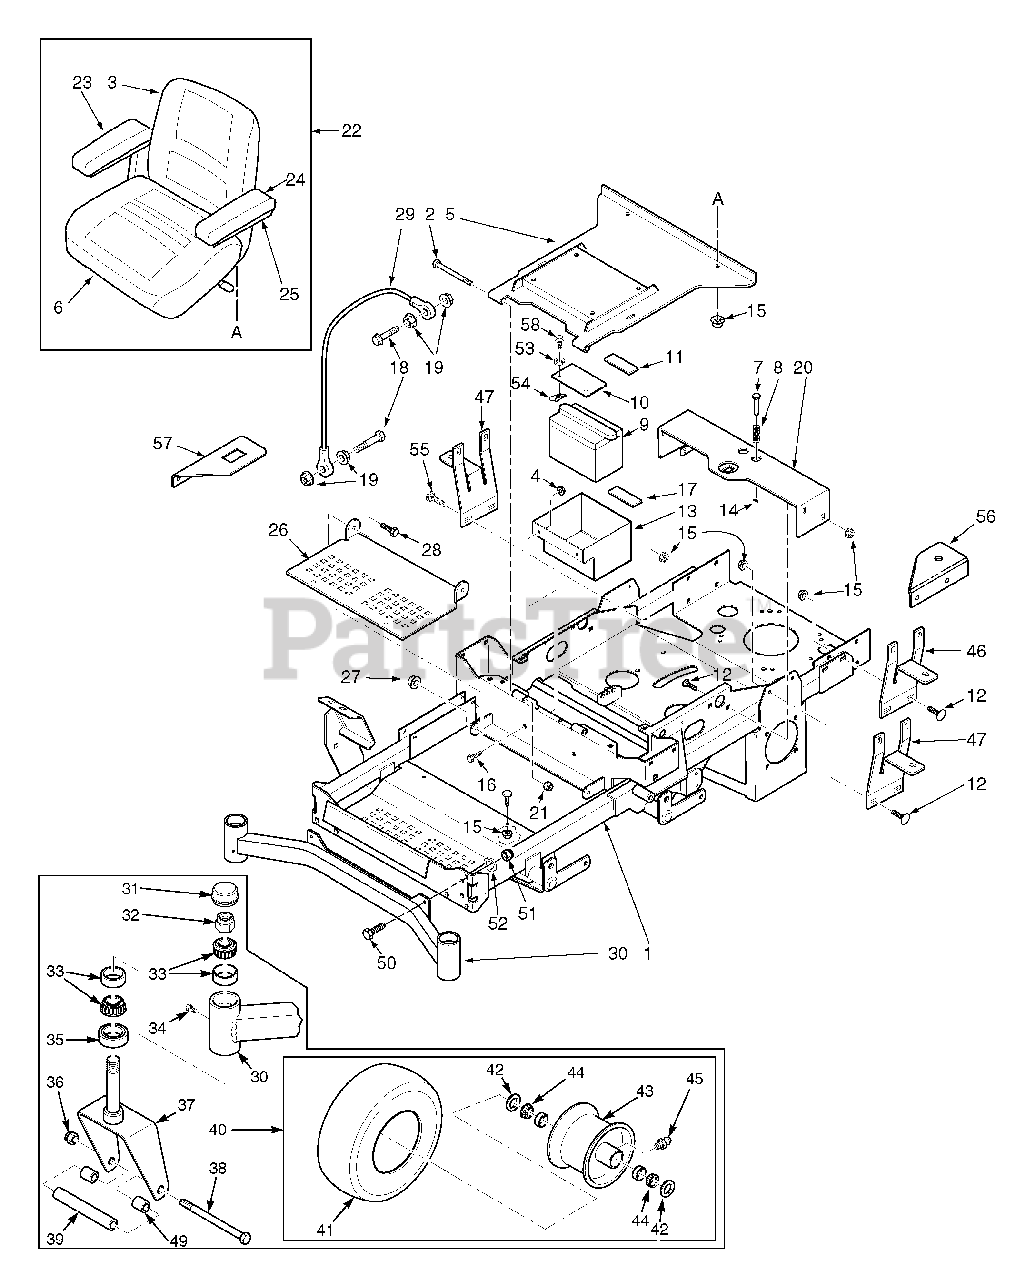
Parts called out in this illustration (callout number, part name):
1	Main Frame Assembly w/decals
2	Bolt, Hex Head 5/16-18 x 3-3/4"
3	Cushion, Back
4	Nut, Serr. Flange 3/8-16
5	Plate, Seat Mounting
6	Cushion, Lower Seat
7	Pin Retainer, Spring
8	Spring
9	Battery
10	Battery Cover
11	Battery Hold Down Pad
12	Bolt, Carr. 5/16-18 x 3/4"
13	Battery Box
14	Roll Pin, Spring 5/32 x 3/4"
15	Nut, Serr. Flange 5/16-18
16	Bolt, Hex Head 3/8-16 x 1"
17	Pad, Rubber
18	Bolt, Hex Head 1/4-20 x 1-1/4"
19	Nut, Serr. Flange 1/4-20
20	Seat Base Support
21	Nut, Elastic Stop 5/16-18
22	Seat Assembly w/ adj. rails
23	Arm Pad, RH
24	Arm Pad, LH
25	Channel, Armrest
26	Footplate
27	Nut, Elastic Stop 3/8-16
28	Bolt, Hex Head 3/8-16 x 1"
29	Cable, Seat Stop
30	Weldment, Caster Support
31	Cap, Grease
32	Nut, Elastic Stop 1.0-14
33	Bearing Set
34	Plug, 1/4-28
35	Seal, 2.0" OD x 1.625" ID
36	Nut, Elastic Stop 1/2-13
37	Yoke, Front Caster Wheel
38	Bolt, Hex Head 1/2-13 x 7-1/2"
39	Sleeve
40	Caster Wheel Assembly
41	Tire, 13 x 5.0-6 Smooth
43	Rim
44	Roller Bearing
45	Fitting, Grease
46	Mounting Bracket, Oil Tank
47	Mounting Bracket, Fuel Tank
48	Seat Pan
49	Spacer, Caster Wheel
50	Bolt, Hex Head 7/16-14 x 1-1/4"
51	Nut, Elastic Stop 7/16-14
52	Lockwasher, 7/16
53	Lock Washer. 3/8 Spring
54	U-Nut, 3/8-16
55	Bolt, Carriage 5/16-18 x 1"
56	Bracket, Fuel Valve
57	Bracket, Hour Meter
58	Bolt, Hex Head 3/8-16 x 1-1/4"
